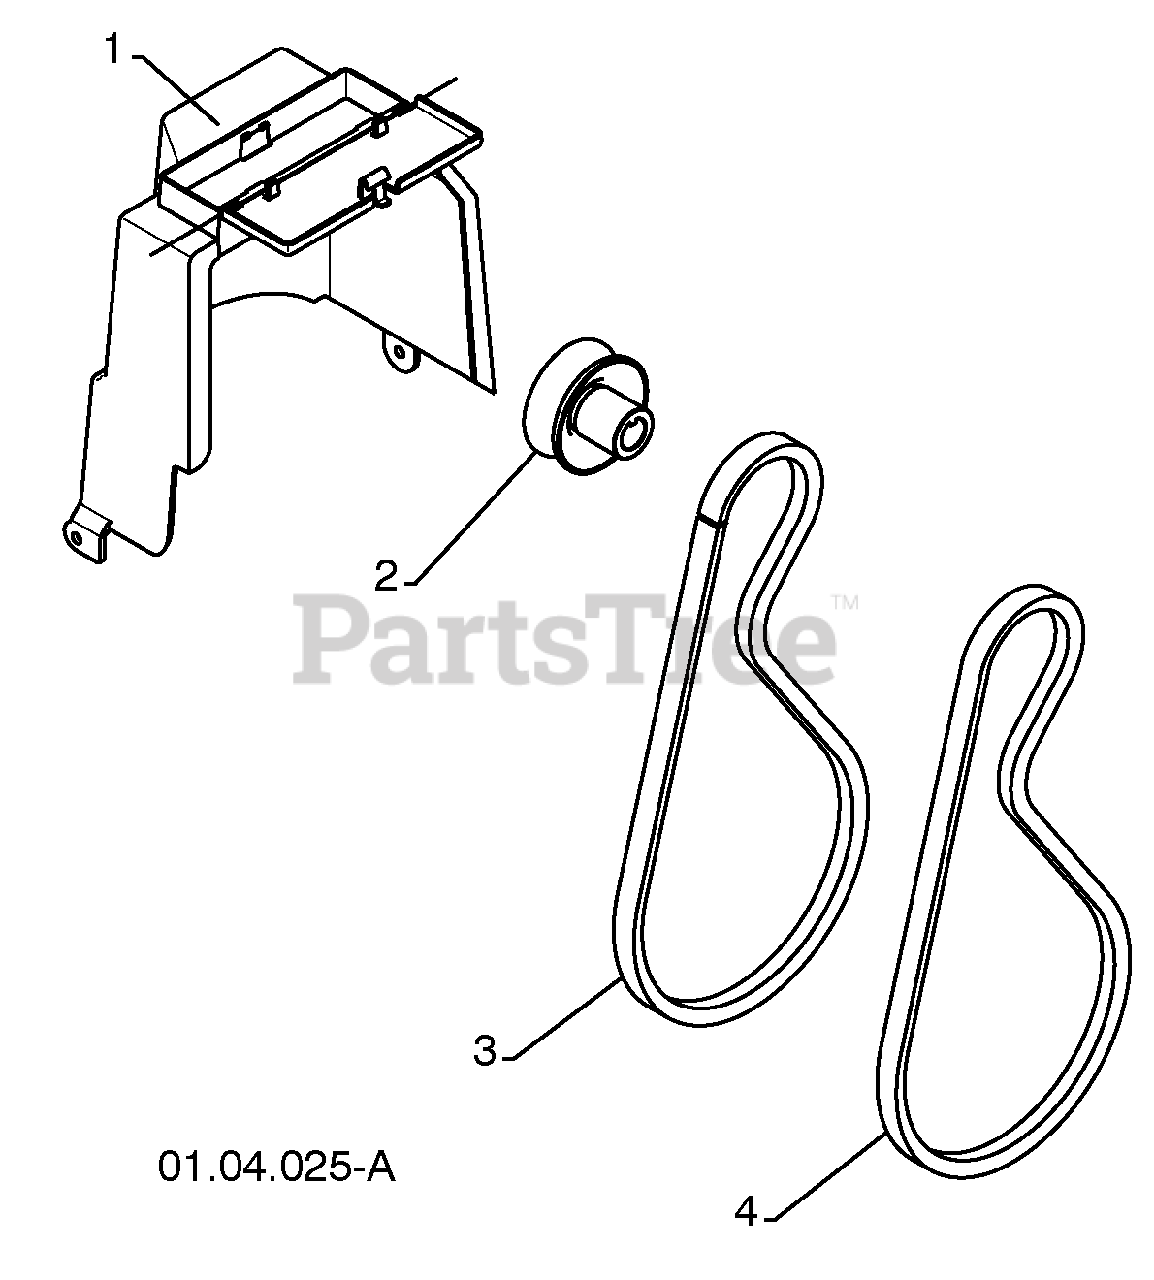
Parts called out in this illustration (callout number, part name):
1	BELT COVER
2	IMPELLER PULLEY
3	TRACTION BELT
4	IMPELLER BELT
